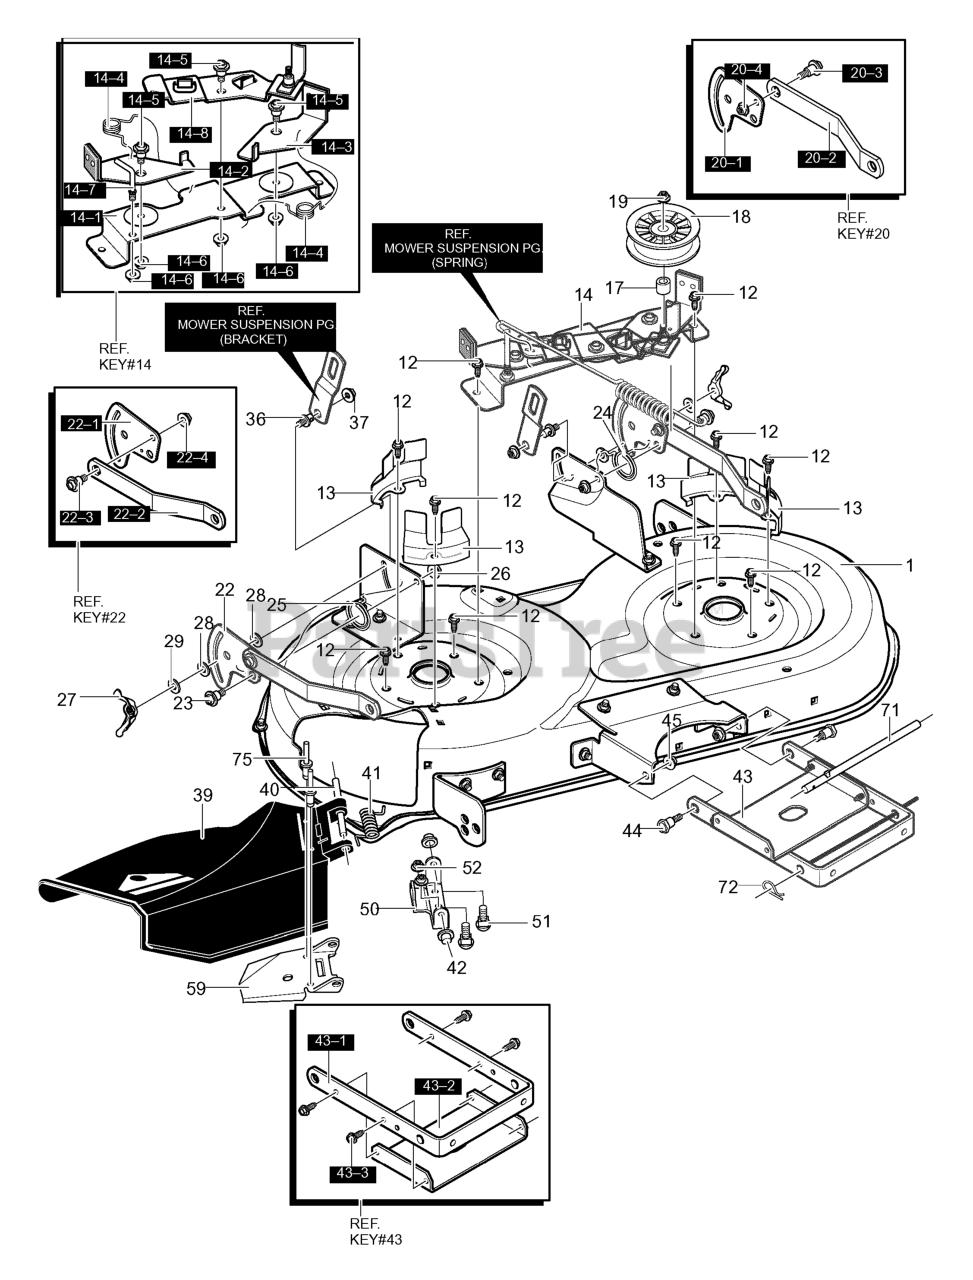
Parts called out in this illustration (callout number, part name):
1	Blade Housing Assembly
12	Engine Bolt 3/8x1.25
13	Cover, Segment Belt Guide
14	Asm., Brkt supt w/Brakes
14-1	Bracket, Brake Mtg.
14-2	Assy., Brake RH
14-3	Assy., Brake LH
14-4	Torsion Spring
14-5	Bolt, 3/8-16 HHSH
14-6	Nut, .38-16 Flng Ctrlk
14-7	Screw Guide
14-8	Assy., Idler Arm
14-9	Nut, .32-18 Flng Ctrlk
17	Spacer, 1/2 to 17MM
18	Idler Pulley
19	Nut, 3/8-16 Hwdfllk Mack
20	Asm., Plate Rear Sus. Brkt LH
20-1	Plate-Suspension
20-2	Suspension Bracket Rear
20-3	Bolt, Shoulder
20-4	Nut, 3/8-16
22	Assy, Plate,Rear Sus Bkt RH
22-1	Plate-Suspension
22-2	Suspension Bracket Rear
22-3	Bolt, Shoulder
22-4	Nut, 3/8-16
23	Bolt, Shoulder
24	Spring, Torsion LH
25	Spring, Torsion RH
26	Nut, 3/8-16
27	Wingnut, 5/16-18
28	Pad, Friction
29	Washer
36	Pin, Hanger
37	Nut, 3/8-16
39	Deflector Chute
40	Rod, Chute Deflector
41	Spring, Torsion
42	Nut, Push Cap
43	Asm., Bracket & Stiffener
43-1	Bracket, Front Suspension
43-2	Stiffener
43-3	Screw, 5/16-18 x 0.75
44	Bolt, Shoulder .375
45	Nut, 3/8-16 Wdfllk Mack
50	Bracket, Chute Attach
51	Carr. Bolt, 5/16-18x.63
52	Nut, 5/16-18 Wdfllk
59	Deflector Support
71	Rod, Hanger
72	Hair Pin
75	Rivet, Semi
